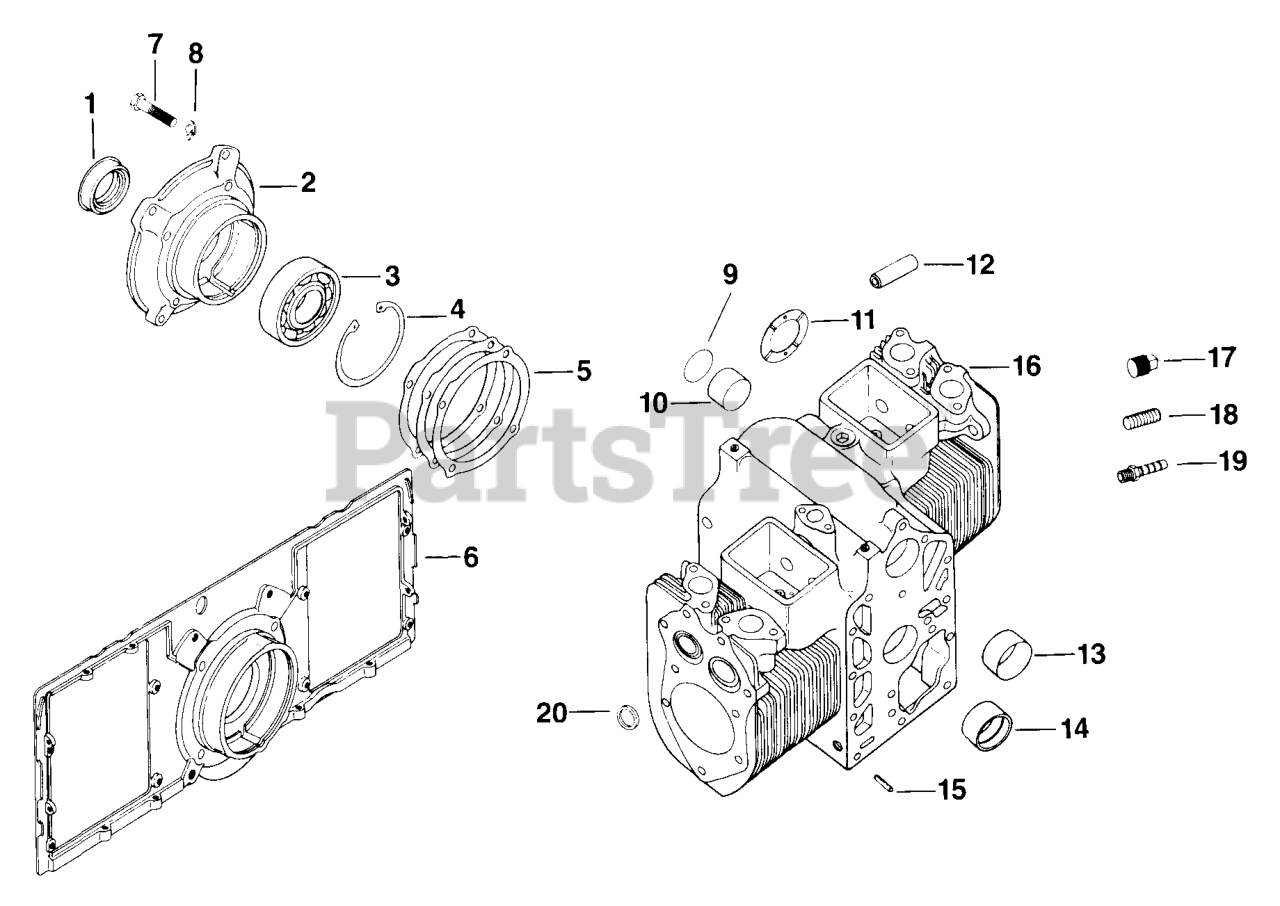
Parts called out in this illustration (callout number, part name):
2	PLATE - DISCONTINUED
3	BEARING
4	RING (#DSC)
7	BOLT, HEX CAP USE 25 086 116-S
8	WASHER, SPRING LOCK 3/8"
10	BUSHING - (#DSC)
12	GUIDE, VALVE - DISCONTINUED
13	BUSHING - USE 48 158 03-S
14	BEARING - USE 48 030 06
14	BEARING, MAIN .010
14	BEARING, MAIN - DISCONTINUED
15	PIN-DISCONTINUED
16	BLOCK - DISCONTINUED
17	PLUG - DISCONTINUED
18	PLUG, CTSK PIPE 1/8" USE 25 139 60-S
